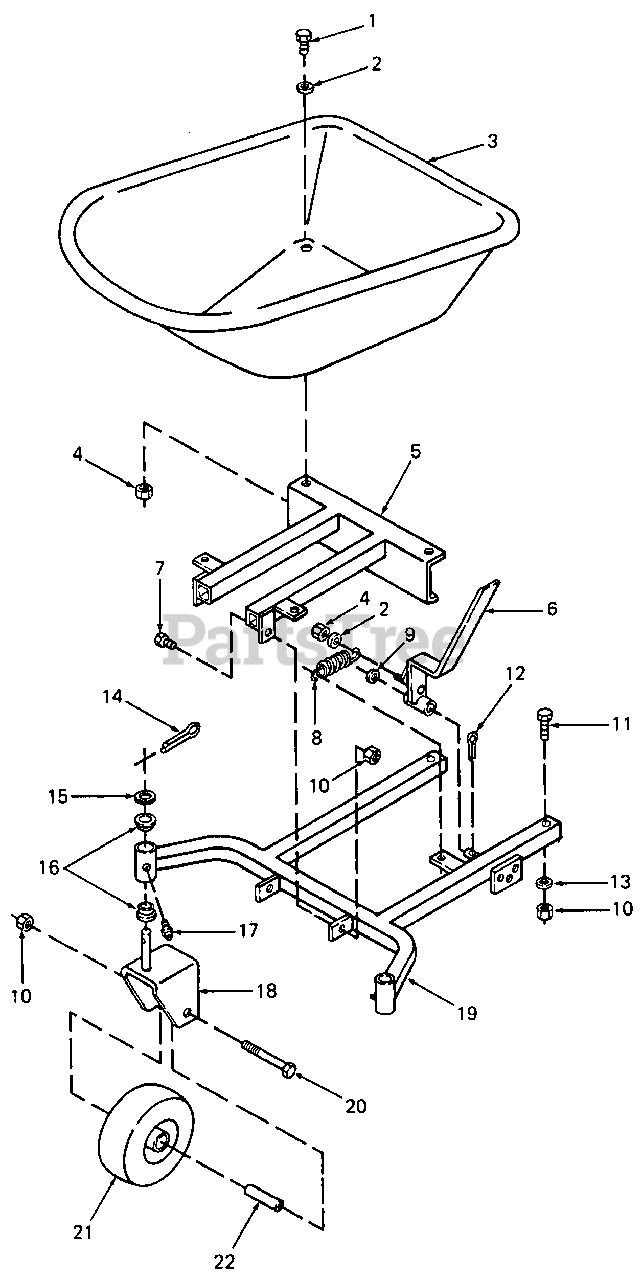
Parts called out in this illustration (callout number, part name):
1	Bolt, Hex, 3/8-16 X 1.0
2	Washer, Flat, 3/8
3	Tray, Poly
4	Nut, Lock, 3/8
5	Weldment, Cart Tray Frame
6	Weldment, Handle
7	Bolt, Hex, 1/2-13 X 1.0
8	Spring, Idler (Extension)
9	Washer, Flat, 5/8
10	Nut, Lock, 1/2
11	Bolt, Hex, 1/2-13 X 2.0
12	Pin, Cotter, 3/16 X 1-1/2
13	Washer, Lock, 1/2
14	Pin, Cotter, 1/4 X 2.0
15	Washer, Flat, 1
16	Bushing, Caster Fork
17	Fitting, Grease
18	Weldment, Fork
19	Weldment, Cart Frame
20	Bolt, Hex, 1/2-13 X 5.0
21	Wheel, Pneumatic Gage, 3-1/2 X 9
22	Tube, Caster Wheel Spacer
